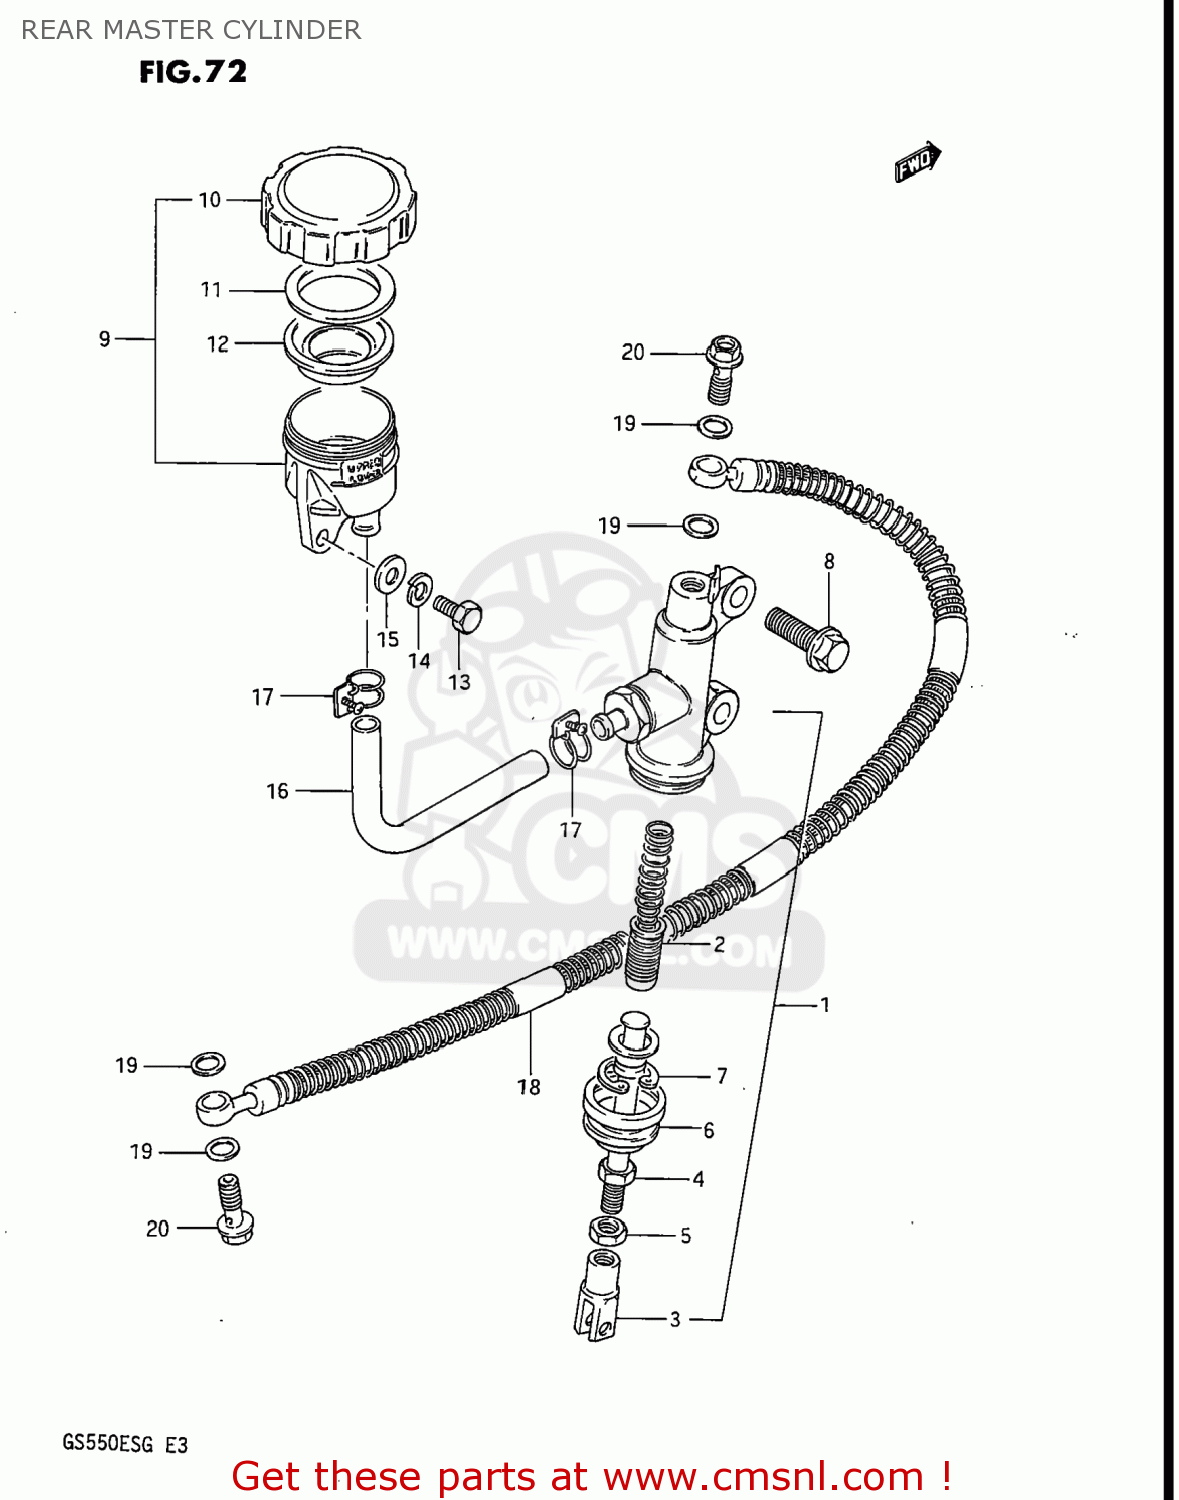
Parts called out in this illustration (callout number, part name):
1	CYLINDER ASSEMBLY,REAR MASTER
2	PISTON/CUP SET
3	YOKE
4	ROD,PUSH
5	NUT,MASTER CYLINDER
6	BOOT
7	CIRCLIP
8	BOLT
9	TANK ASSEMBLY,RESERVOIR
10	CAP
11	PLATE,DIAPHRAGM
12	DIAPHRAGM
13	BOLT, UPPER
14	WASHER,LOCK
15	WASHER
16	HOSE,RESERVOIR TANK
17	CLAMP
18	HOSE,REAR BRAKE
19	WASHER(10X15X1.5)
20	BOLT UNION
